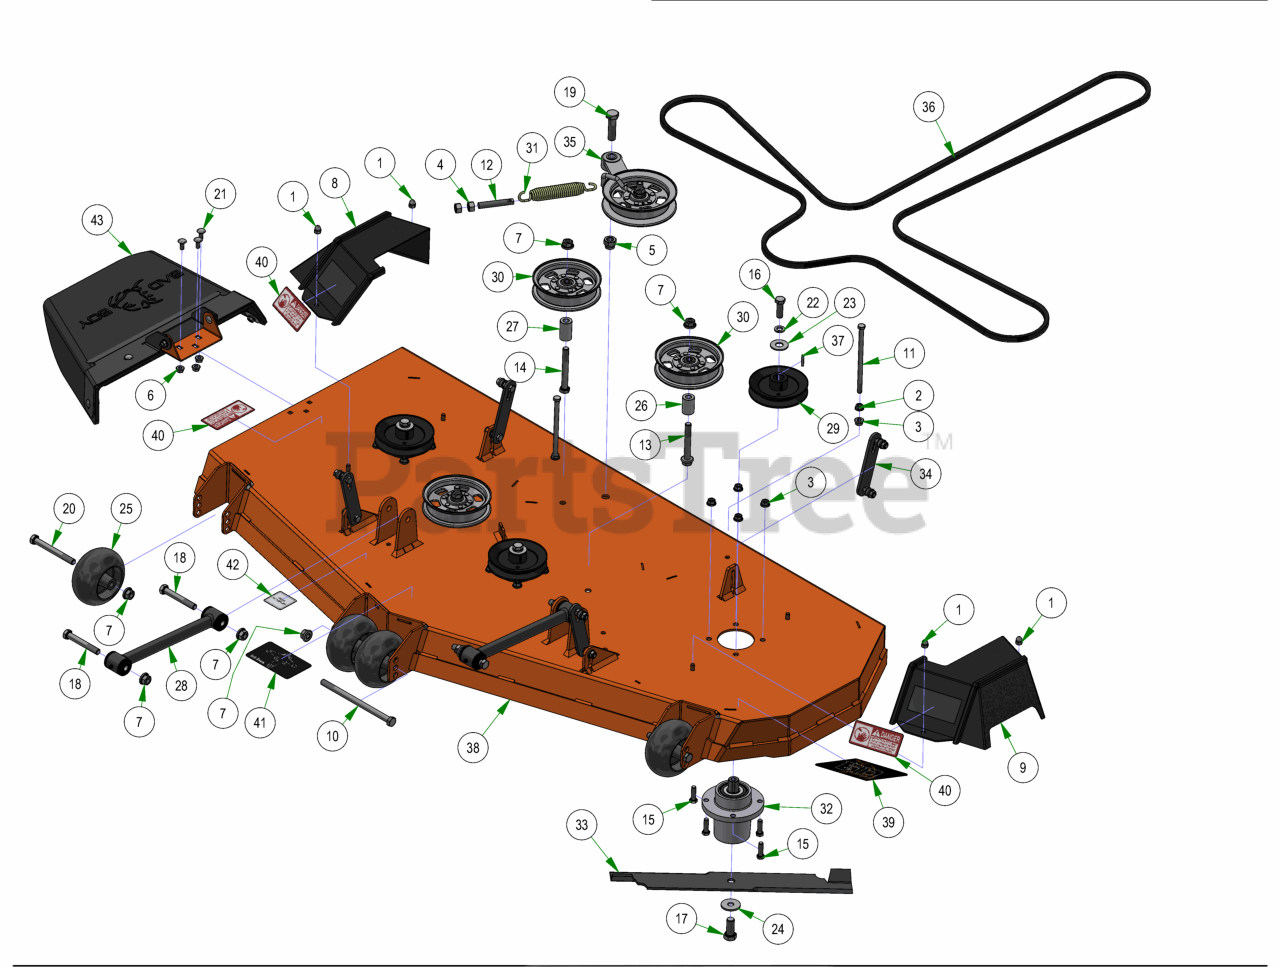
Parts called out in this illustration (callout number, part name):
1	5/16-18 ACORN NUT HIGH-CROWN ZC
2	3/8-16 HEX SERRATED FLANGE NUT HARD/ZINC
3	3/8-16 NYLON INSERT FLANGE LOCKNUT (GR.F) ZINC
4	1/2-13 HEX NUT ZINC
5	5/8-11 NYLON INSERT LOCKNUT ZINC
6	5/16-18 NYLON INSERT FLANGE LOCKNUT ZINC
7	1/2-13 NYLON INSERT FLANGE LOCKNUT ZINC
8	2021 Maverick 54”/60” RH Pulley Cover
9	2021 Maverick 54”/60” LH Pulley Cover
10	1/2-13 X 8 HEX CAP SCREW GR 5 ZINC
11	3/8-16 X 6.5 HEX CAP SCREW (GR.5) ZINC
12	All Thread
13	1/2-13 X 3-1/2 HEX FLANGE BOLT (GR.8) ZINC
14	1/2-13 X 4 HEX CAP SCREW (GR.8) ZINC YELLOW
15	3/8-16 X 1-1/4 HEX CAP SCREW (GR.5) ZINC
16	1/2-20 X 1-1/2 HEX CAP SCREW (GR.5) ZINC
17	5/8-18 X 1-1/2 HEX CAP SCREW (GR.8) ZINC YELLOW
18	1/2-13 X 3-1/2 HEX CAP SCREW (GR.5) ZINC
19	5/8-11 X 2-1/4 HEX CAP SCREW (GR.5) ZINC
20	1/2-13 X 4-1/2 HEX CAP SCREW (GR.5) ZINC
21	5/16-18 x 3/4 Carriage Bolt
22	1/2 SPLIT LOCKWASHER (GR.8) ZINC/YELLOW
23	5/8 USS FLAT WASHER (1-3/4" OD) GR.8 ZINC YELLOW
24	1/2 BELLEVILLE WASHER (1-5/8 OD X .140 THK) ZINC
25	2019 Deck Wheel
26	.502 ID X .750 OD X 1.500 Long Spacer
27	1 3/4" Pulley Spacer
28	Hybrid Turnbuckle/Deck Locator
29	60" MZ Deck Pulley
30	5-3/4 Idler Pulley
31	Deck Idler Spring
32	Spindle Assembly-MZ
33	60" High Lift Fusion Blade
34	Deck Hanger Assembly
35	Maverick HD & Down Deck Idler Assembly
37	3/16 X 1 SQ MACHINERY KEY 1018 STL ZINC
38	2025 60" 4in Deck Weldment
39	60" Grip Deck Decal
40	Danger Decal-Spindle/Discharge
41	Deck Belt Route Decal
42	Deck Impact Patent Decal 9591803
43	MZ Discharge Chute Assembly
